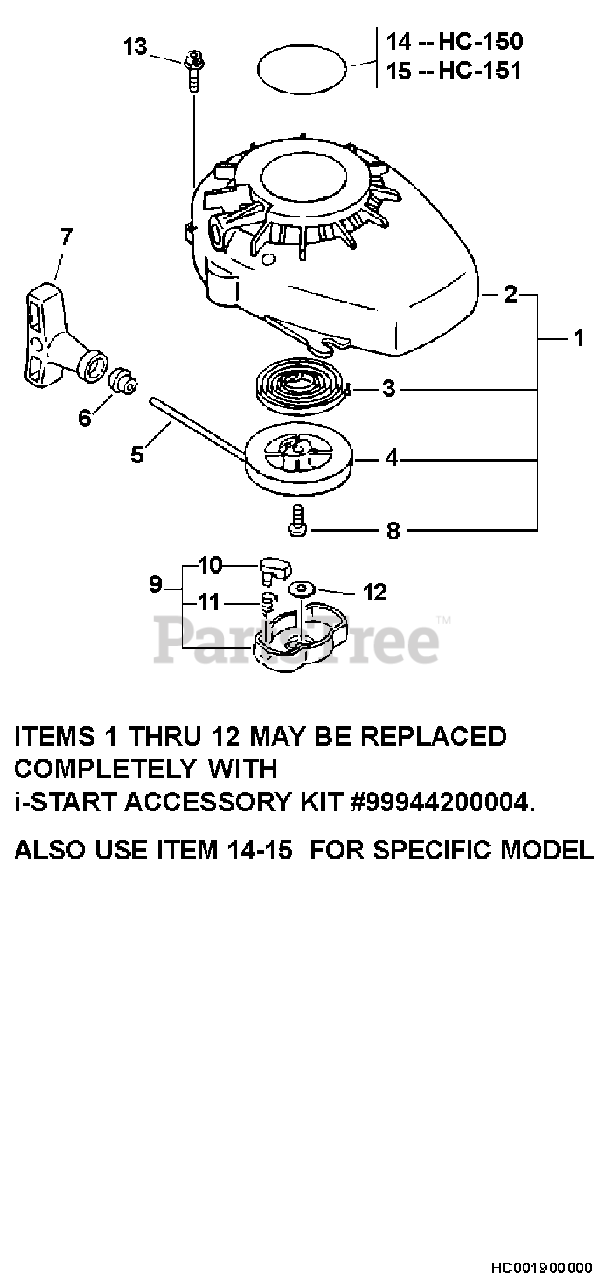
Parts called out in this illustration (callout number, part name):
1	STARTER ASSY
2	CASE, FAN
3	SPRING, RECOIL
4	REEL, ROPE
5	ROPE, STARTER 3.0×1000
6	GUIDE, ROPE
7	GRIP, STARTER
8	SCREW
9	PAWL ASSY, STARTER
10	PAWL, STARTER - BLACK
11	SPRING, RETURN
12	WASHER, SPRING 8
13	BOLT 4×16
14	LABEL - MODEL HC-150
15	LABEL, MODEL
